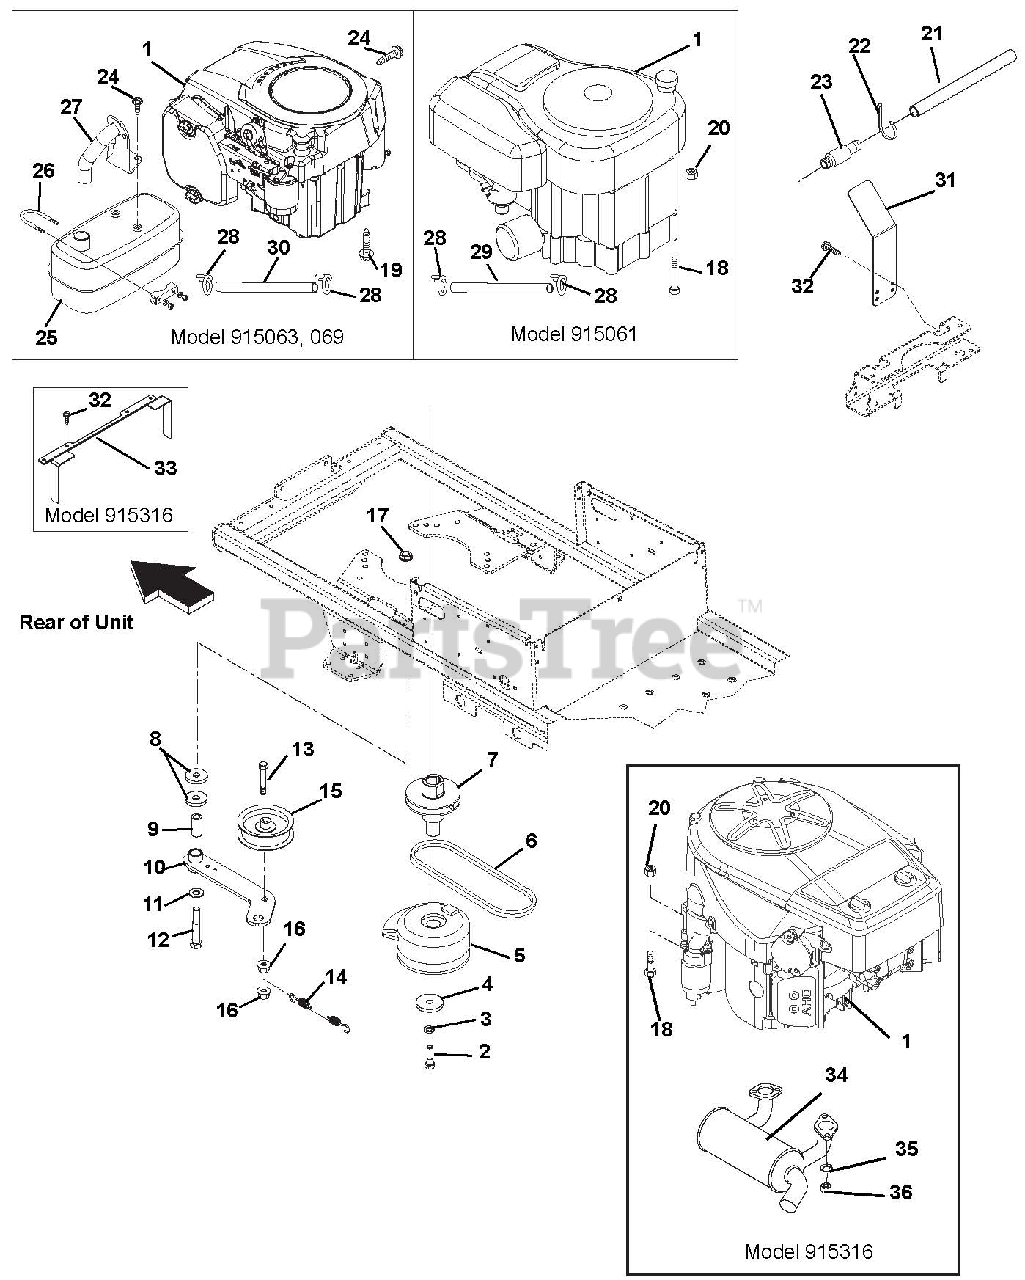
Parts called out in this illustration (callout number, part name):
1	ENGINE, 15HP KOLHER
1	ENGINE,28 CI B&S I/C
1	ENGINE, 15HP KAW FH451V
2	BLT-HEX .44-20X4.50 GR8 YWZC
3	@WSHR-LK .44X.109 REG YWZC
4	WSHR-FL-STL .469X2.00X.25 YWZC
5	ELECTRIC CLUTCH/BRAKE (3.4AMP)
6	V-BELT, HA-RAW EDGE
7	CRANKSHAFT EXTENSION
8	WSHR-FL-STL .515X1.625X.250 YZ
9	BSHG-SLV .500X.750X1.560
10	WMT,IDLER
11	@WSHR-FL-STL.531X1.06X.095YWZC
12	@BLT-HEX .50-13X3.25 GR5 YWZC
13	@BLT-HEX .38-16X2.00 GR5 YWZC
14	SPRING, EXT
15	IDLER FLANGED 3.50
16	@NUT-LK-NYL-FLG .38-16 YWZC
17	@NUT-LK-TOP-FLG .50-13 YWZC
18	@BLT-HEX .31-18X1.75 GR5 YWZC
19	@SCR-TAP .38-16X1.00 HWH TR YZ
20	@NUT-LK-NYL-FLG .31-18 YWZC
21	TUBE, OIL DRAIN
22	CABLE TIE LG 5-1/2
23	VALVE, OIL DRAIN
24	@SCR-TAP .25-20X.50 HWH TR YWZ
25	MUFFLER, KOHLER COURAGE SINGLE
26	MUFFLER CLAMP
27	WMT, MANIFOLD
28	CLAMP-HOSE WIRE .490/.510X.116
29	GAS LINE-BULK 1/4" I.D.
30	GAS LINE-BULK 1/4" I.D.
31	HEAT SHIELD,MINI-Z
32	@SCR-TAP .31-18X.50 HWH TR YWZ
33	HEAT SHIELD
34	MUFFLER, KAW. (COMPACT-Z)
35	@WSHR-LK .31X.078 REG YWZC
36	NUT-HEX M8-1.25 YWZC
